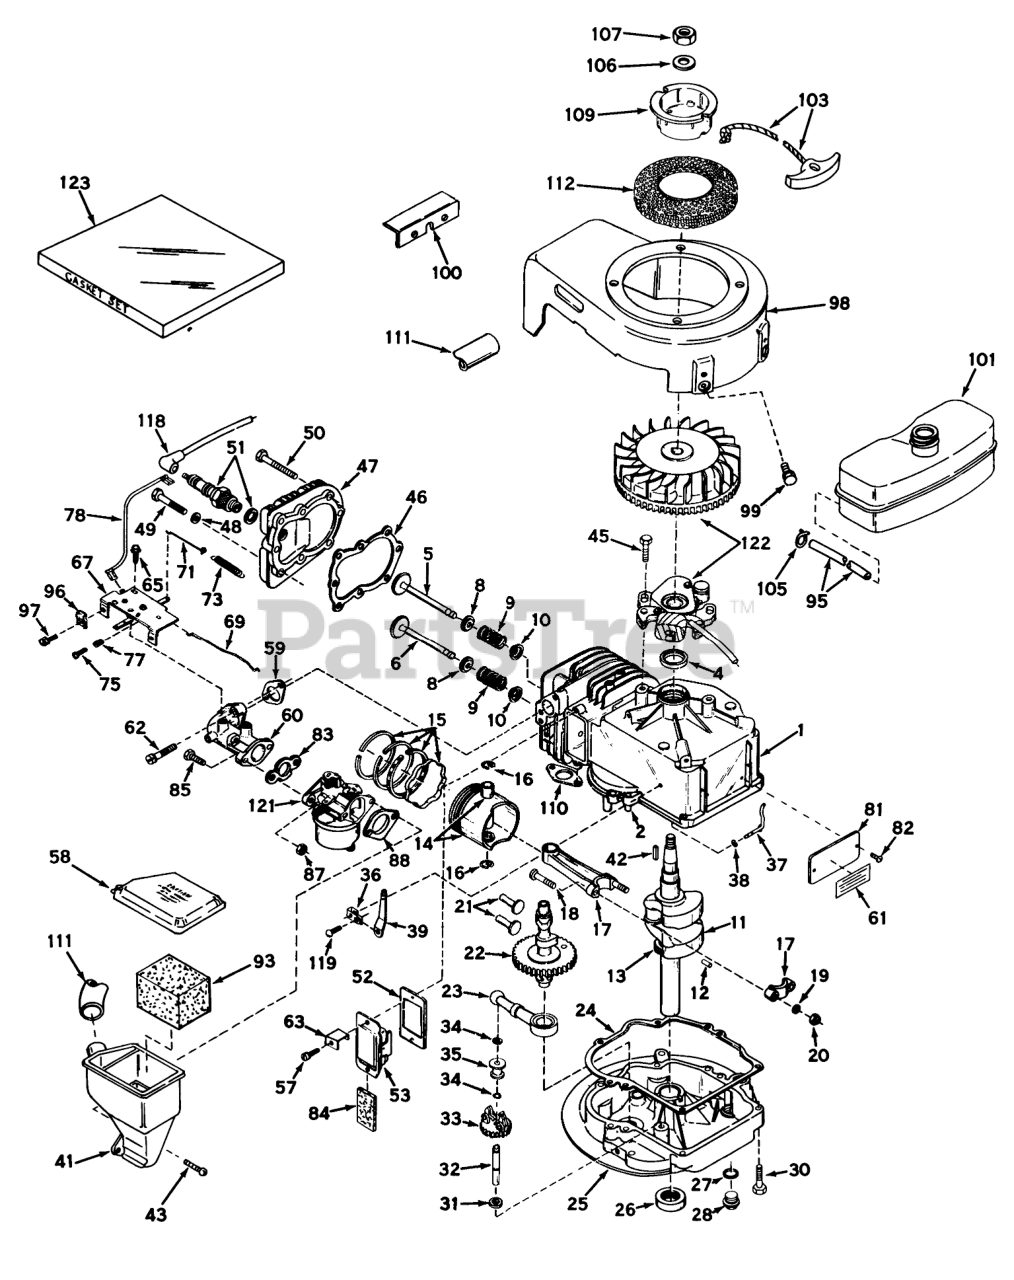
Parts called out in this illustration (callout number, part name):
1	Cylinder Assy. (Incl. Ref. Nos. 2 & 4)
2	Pin-Dowel
4	OIL SEAL
5	Valve, Intake (Std.)(Incl. Nos. 8, 9 & 10)
5	Valve, Intake (1/32" Over size)(Incl. Nos.8, 9 & 10)
6	Valve, Exhaust (Std.)(Incl. Nos. 8, 9 & 10)
6	Valve, Exhaust (1/32" Over size (Incl. Nos. 8, 9 & 10)
8	Cap-Upper Valve Spring
9	Spring-Valve
10	Cap-Valve, Spring
11	Crankshaft Assy. (Incl. Nos. 12 & 13)
12	Pin, Groove
13	Gear, Crankshaft
14	Piston & Pin Assy. (Incl. 2 of No. 16)(Std.)
14	Piston & Pin Assy. (Incl. 2 of No. 16)(.010 Oversize)
14	Piston & Pin Assy. (Incl. 2 of No. 16)(.020 Oversize)
15	Piston Ring Set Std.
15	Piston Ring Set .010 O.S.
15	Piston Ring Set .020 O.S.
16	Ring-Retaining, Piston Pin
17	Rod Assy., Connecting (Incl. Nos. 18, 19 & 20)
18	Bolt, Connecting
20	LOCKNUT
21	Lifter-Valve
22	Camshaft
23	Oil Pump ASM
24	Gasket, Mounting
25	Flange Assy., Mtg. (Incl. Nos.26, 27, 28 & 32)
26	Seal Oil
27	Gasket-Oil Drain
28	Plug Oil Drain
30	Screw (1/4-20 x 1-1/4)
31	Washer-Flat
32	Shaft-Governor
33	Governor Gear ASM
34	Ring-Retaining
35	Spool-Governor
36	Clamp-Lever, Governor
37	Rod, Governor (Incl. No.38)
38	Washer-Flat
39	Governor Lever
41	Body, Air Cleaner
42	Key Flywheel
43	Screw, Fil. Hd. Sems
46	Gasket-Cylinder Head
47	CYLINDER HEAD
49	Screw
50	Screw Hex Hd. Cap
51	SPARK PLUG
52	Gasket Breather
53	Breather Assy. (Incl. Nos. 52 & 84)
58	Cover, Air Cleaner
59	Gasket, Intake
60	Pipe, Intake
61	480B GIL SNWTHWR O/
62	Screw, Fil. Hd. Sems
63	Retainer Clip
65	Screw (10-24 x 9/16)
67	Control Assy., Speed
69	Link, Throttle to Governor
71	Link-Governor
73	Spring, Governor
75	Screw
77	Spring-Compression
78	Wire, Ground
81	IDENTIFICATION PLATE
84	Element-Breather
85	Screw (1/4-28 x 7/8)
87	Nut and Lock Washer (1/4-28)
88	Gasket-Air Cleaner
93	Element, Air Cleaner
95	Line-Fuel (8.62)
96	Conduit
97	Screw (10-32 x 3/8)
98	Housing, Blower
99	Screw (1/4-20x19/32)
100	Bracket, Shroud
101	Tank, Fuel
103	Rope Assy., Starter
105	Clamp-Line, Fuel
106	Washer
107	Hex Nut
109	Pulley Starter
110	Gasket Exhaust
111	Tube, Air Cleaner
112	Screen, Air
118	Cover-Spark Plug
119	Screw
121	Carburetor
122	Magneto
123	Gasket Set
